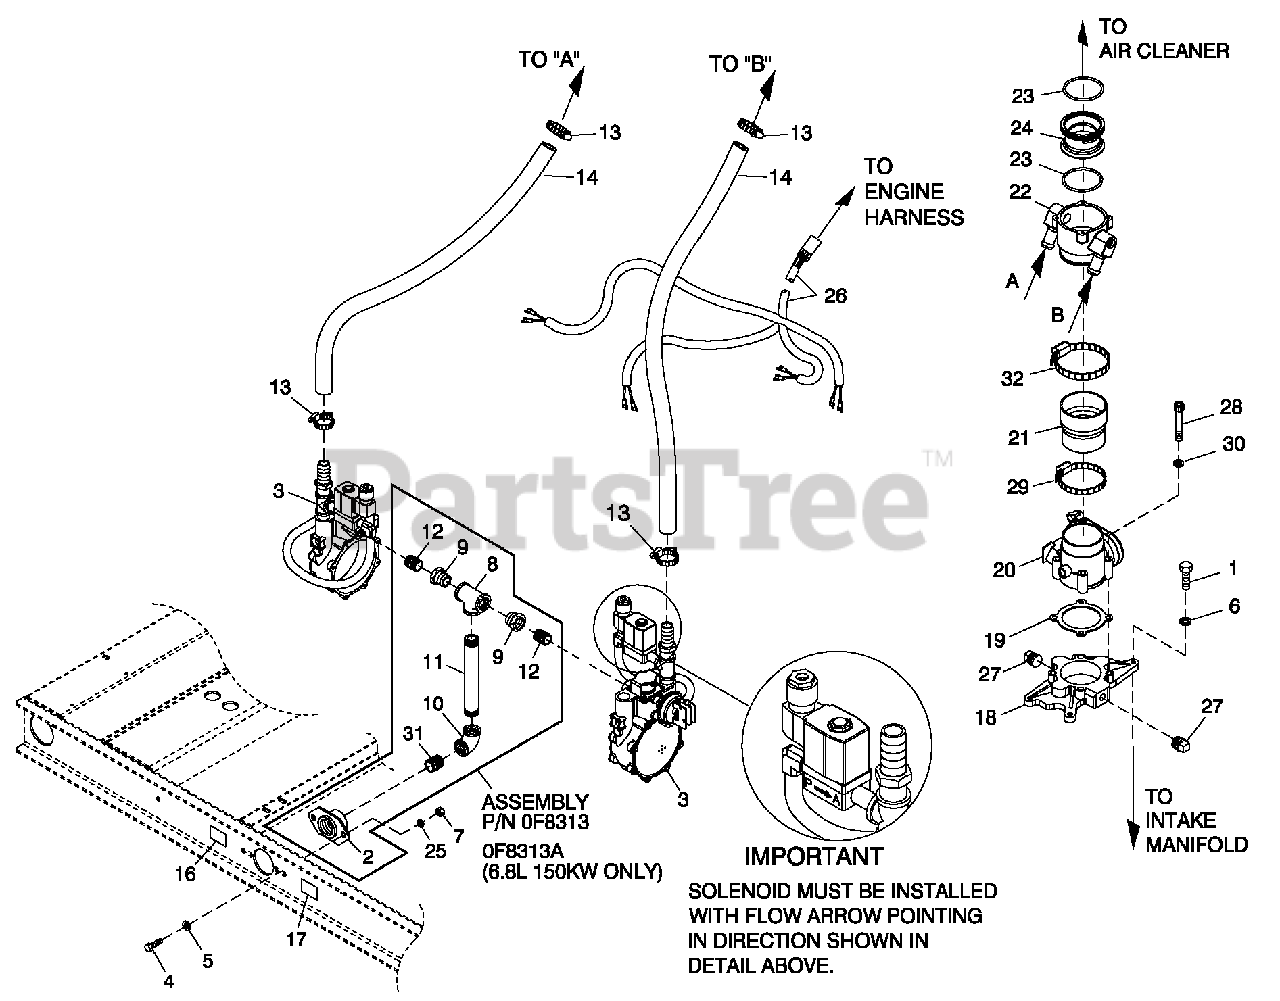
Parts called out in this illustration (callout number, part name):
1	SCREW HHC 5/16-18 X 1-1/4 G5
2	SUPPORT NAT GAS SOLENOID
3	REG ASSY 5.4L 80 KW LPV CPL
4	SCREW HHC #12-1.75 X 20 G8.8
5	WASHER FLAT 1/2 ZINC
6	WASHER LOC K M8-5/16
7	NUT HEX M12-1.75 G8 YEL CHR
8	PIPE TEE 1-1/4 NPT
9	BSHGRDCR HEX1-1/4-3/4
10	ELBOW 90D1-1/4 NPT
11	NIPPLE PIPE 1-1/4 NPT X 3 (100 KW & 130 KW)
12	NIPPLE CLOSE 3/4X1.375
13	CLAMP HOSE #10 .56-1.06
14	HOSE 3/4 ID SAE-30R2 (45" LG)
15	CLAMP HOSE #52 2.81-3.75
16	DECAL INLET PRESSURE
17	DECAL FUEL INLET LPG
18	MACHINING, INTAKE ADAPTOR 60MM
19	GAS KET GOVERNOR ACTUATOR
20	ACTUATOR BOSCH 60 GOVERNOR
21	REDUCER 3.0" TO 2.75" TURBO
22	MIXER 40/60MM ACTUATOR ASSY
23	O-RING 2-3/4X3/32X2-15/16
24	VENTURI, THROTTLE 38MM
25	WASHER LOC K1/2
26	HARN FUEL JUMPER DUAL REG
27	PLUG STD PIPE 1/4 STEEL SQ HD
28	SCREW SHC M6-1.0X 50 C8.8
29	CLAMP HOSE #44 2.31-3.25
30	WASHER LOC K M6-1/4
31	NIPPLE CLOSE 1.25 NPT X 1.625
